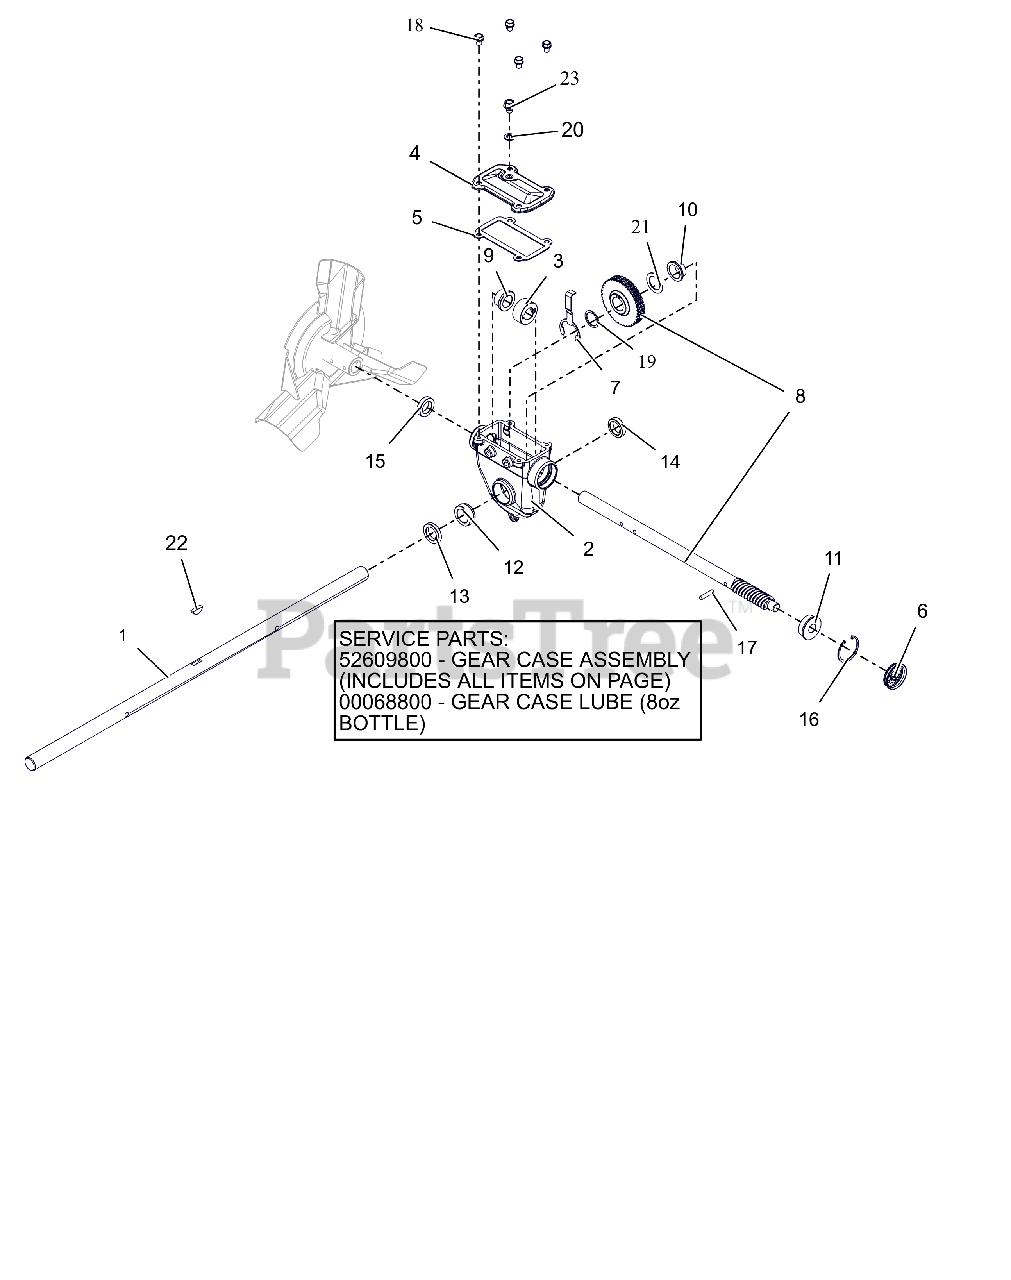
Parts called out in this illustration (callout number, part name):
1	SHAFT, RAKE-32"
2	GEARCASE, LARGE MACHINED
2	GEAR CASE, 32" IRON PRO TOP-LD
2	ARIENS L3 LUBE, 8 OZ BOTTLE
3	THRUST COLLAR, .875"ID SLIPFIT
4	COVER, TOP - LARGE IRON
5	GASKET, TOP - LARGE GEARCASE
6	COVER, GEAR CASE 1.75"
7	BUSHING RETAINER, LARGE
8	ASSY, WORM SHAFT & GEAR
9	BSHG-FLG .879X1.128X.75X1.45
10	BSHG-FLG 1.006X1.128X.555X1.45
11	BSHG-FLG .628X1.503X.58X1.725
12	BSHG-FLG LARGE, RIGHT
13	SEAL-OIL .999X1.500X.250 TBC29
14	SEAL-OIL .999X1.375X.312 TBC29
15	SEAL-OIL .873X1.375X.312 TBC29
16	RG-RTNG-INT 1.750X.062
17	PIN-STR .250X1.12 6150
18	BLT, SEMS .31-18X.50 G5 ZCC
19	WSHR, FLT 1.010X1.250X.068 ZCC
20	WSHR-BND-SEAL .38X.75X.11 GALV
21	WSHR, FLT 1.010X1.505X.062 ZCC
22	KEY-WDRF .25X.875 HRD #A
23	SCR,TAP .38-15X.50 HWH ROLOK
